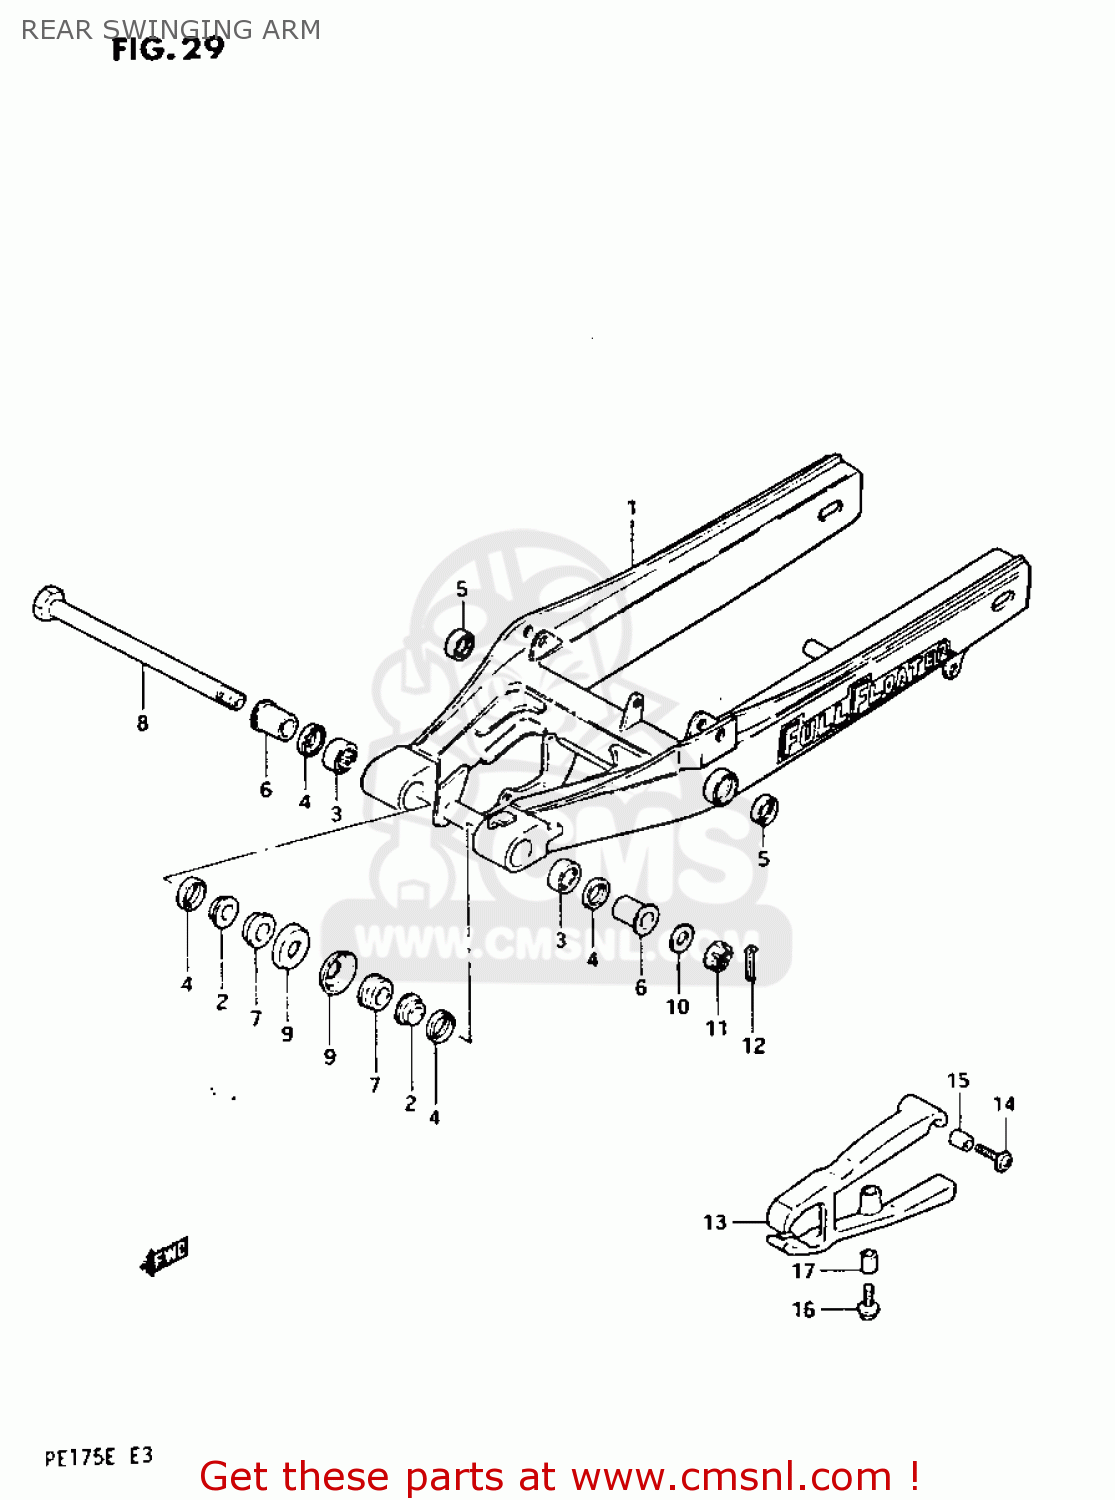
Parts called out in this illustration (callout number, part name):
1	SWING ARM ASSEMBLY,REAR
2	BUSH,RR SWINGINGARM PIVOT
3	BEARING(20X27X20)
4	OIL SEAL
5	OIL SEAL
6	SPACER,RR SWGARM PIVOT
7	SPACER,RR SWGARM PIVOT INNER
8	SHAFT,RR SWINGINGARM PIVOT
9	COVER,RR SWGARM DUST SEAL
10	WASHER
11	NUT 14MM
12	COTTER PIN
13	BUFFER,CHAIN TOUCH DEFENSE
14	BOLT,CHAIN TOUCH DEFEND
15	SPACER (6.1X9X9)
16	BOLT,CHAIN TOUCH DEFEND
17	SPACER(6.5X10.5X22.5)
